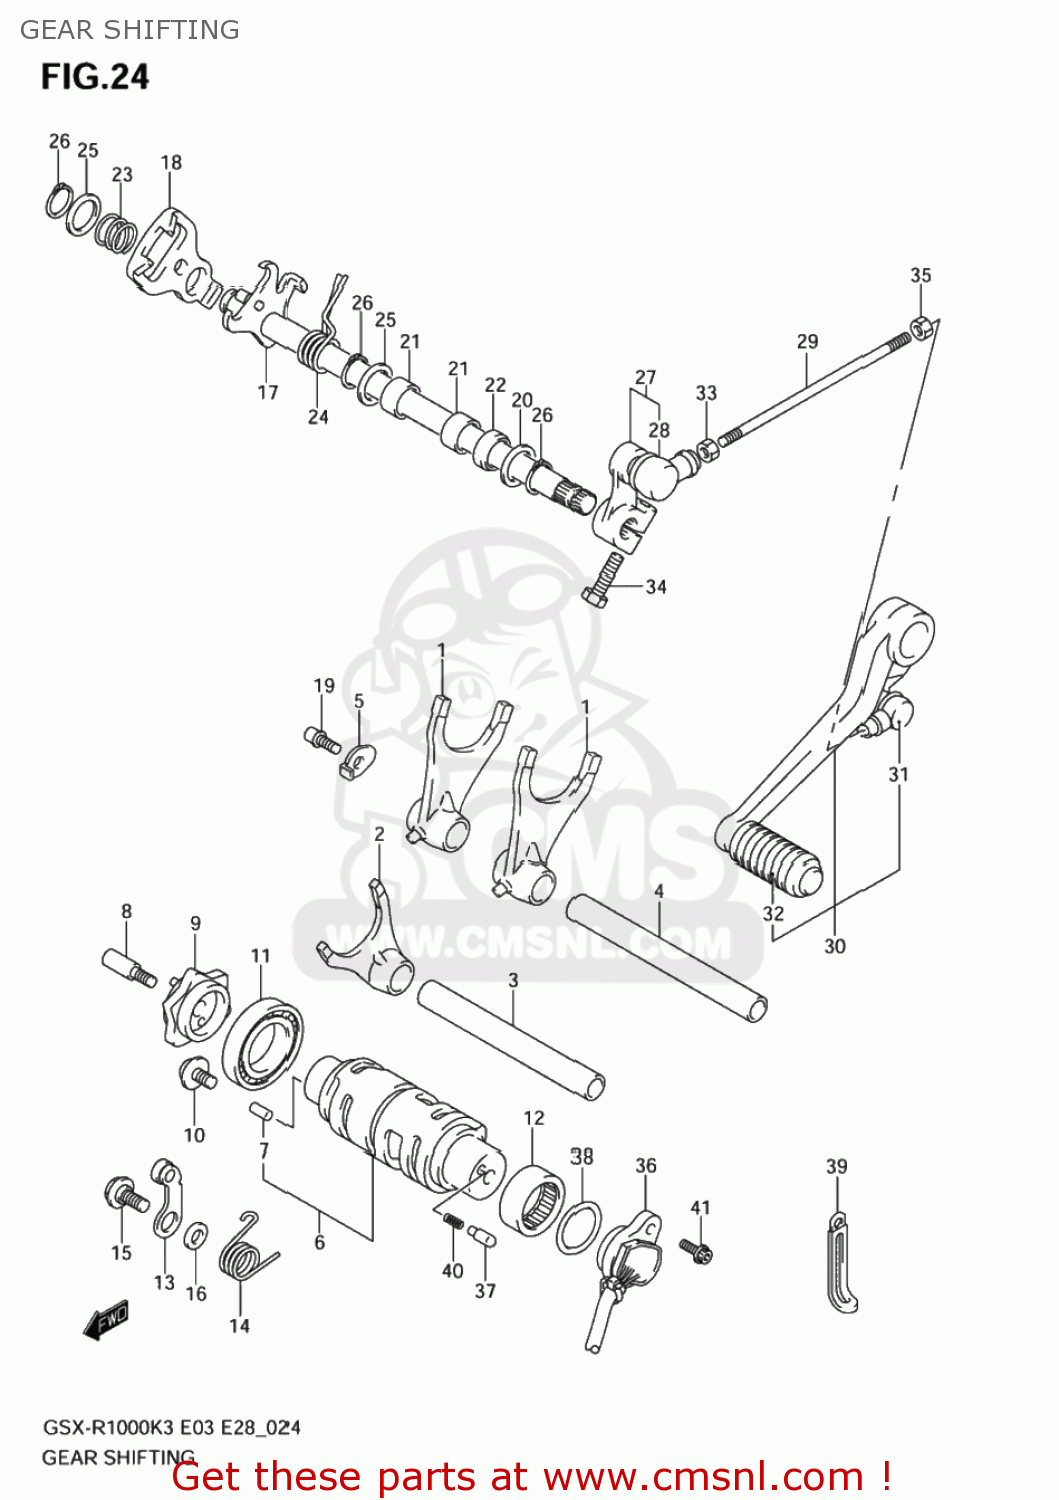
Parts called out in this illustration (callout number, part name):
1	FORK,GEAR SHIFT NO.1
2	FORK,GEAR SHIFT NO.3
3	SHAFT,GEAR SHIFT FORK
4	SHAFT,SHIFT FORK NO.2(L:132)
5	RETAINER,GEAR SHIFT FORK SHAFT
6	CAM,GEAR SHIFT
7	PIN
8	BOLT,GEAR SHIF
9	PLATE,GEAR SHIFT CAM
10	SCREW(6X12)
11	BEARING(25X47X8)
12	BEARING(25X32X12)
13	STOPPER,SHIFT CAM
14	SPRING,SHIFT CAM STOPPER
15	BOLT(6X14.3)
16	WASHER
17	SHAFT,GEAR SHIFT
18	PLATE,GEAR SHIFT CAM DRIVE
19	STOPPER,GEAR SHIFT ARM
20	WASHER(14X29X0.8)
21	BEARING(14X20X12)
22	SEAL,OIL(14X22X6)
23	SPRING
24	SPRING
25	SHIM(14X22X1)
26	CIRCLIP
27	ARM,GEAR SHIFT LINK
28	COVER,DUST
29	ROD,GEAR SHIFT LINK
30	LEVER ASSY,GEAR SHIFT
31	COVER,DUST
32	RUBBER,GEAR SHIFT PEDAL
33	NUT
34	BOLT
35	NUT
36	BASE ASSY,GEAR SHIFT TERMINAL
37	PIN(5X15.5)
38	O RING(D:2.4,ID:25.7)
39	CLAMP(L:45)
40	SPRING
41	BOLT(5X16)
